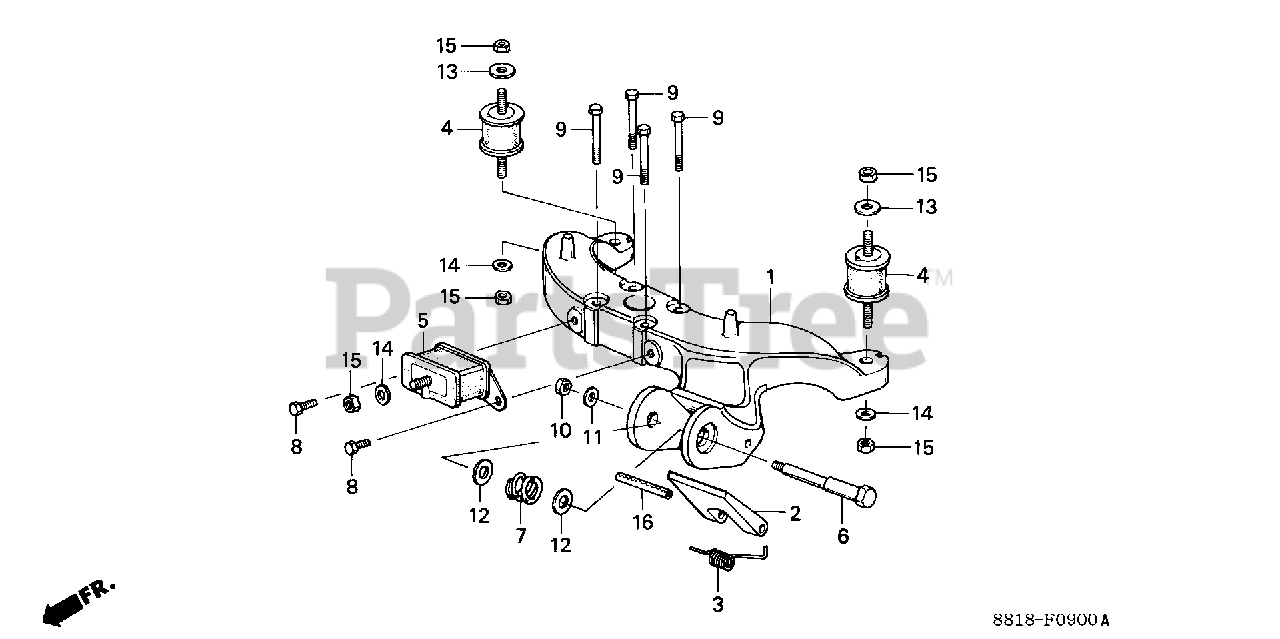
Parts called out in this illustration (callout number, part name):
1	FRAME, MOUNTING *NH282MU* (OYSTER SILVER METALLIC-U)
2	STOPPER, HANDLE *NH282MU* (OYSTER SILVER METALLIC-U)
3	SPRING, HANDLE
4	RUBBER, MOUNTING (UPPER)
5	RUBBER, THRUST MOUNTING
6	SCREW, HANDLE PIVOT
7	SPRING, HANDLE PIVOT
8	BOLT, HEX. (6X14)
9	BOLT, HEX. (6X40)
10	NUT, HEX. (8MM)
11	WASHER, PLAIN (8MM)
12	WASHER (10MM)
13	WASHER (8MM)
14	WASHER, PLAIN (8MM)
15	NUT, HEX. (8MM)
16	PIN, SPRING (6X50)
